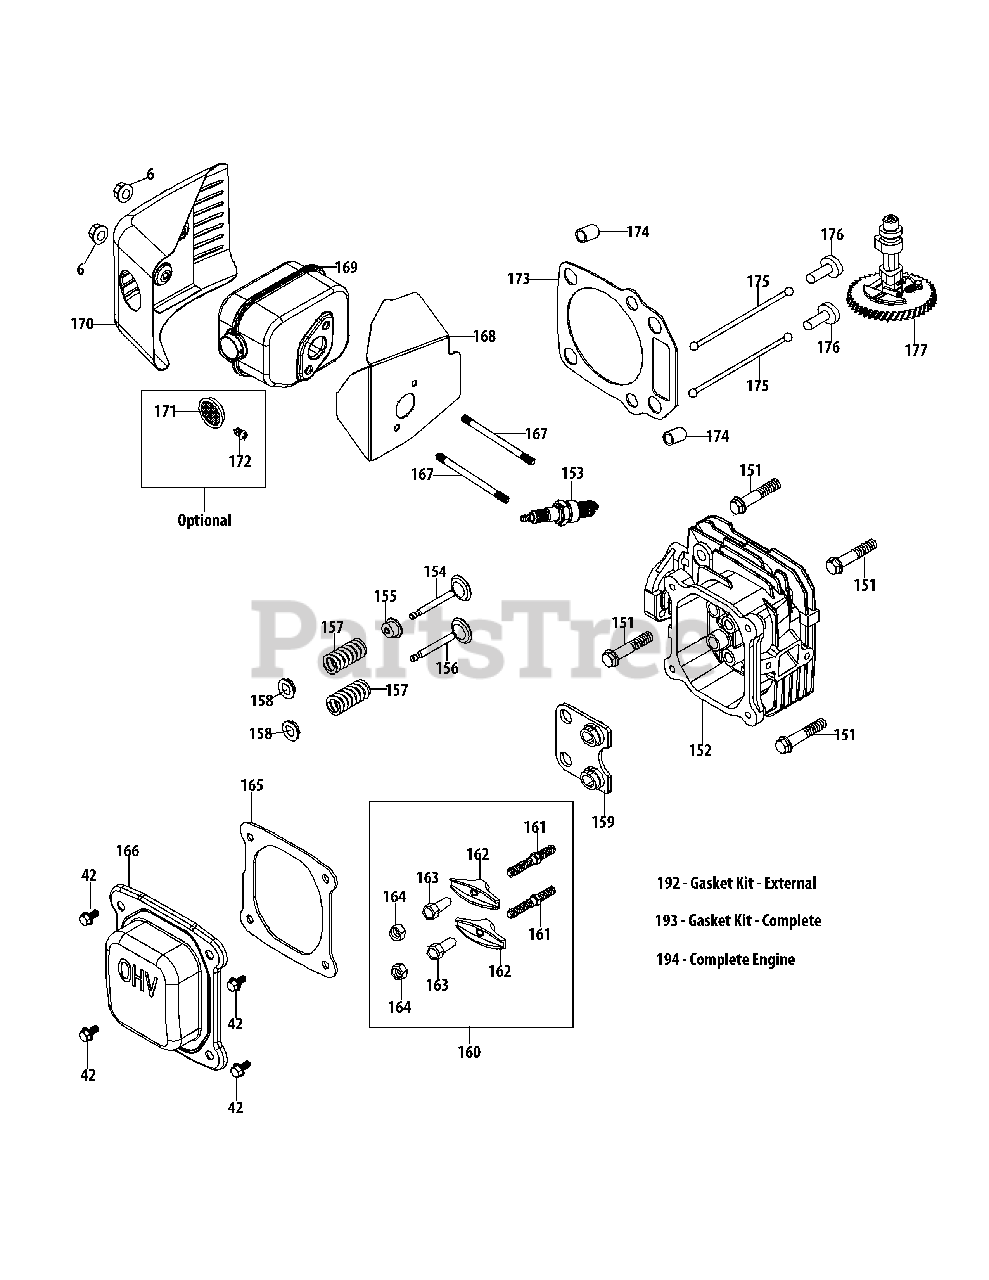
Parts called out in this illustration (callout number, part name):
6	Nut M6 X 10 Mm
42	Bolt M6X14
151	Bolt M8X54
152	Cylinder Head Svc Kit
152	Cylinder Head Assembly
153	Spark Plug/F6Rtc
154	Intake Valve
155	Intake Valve Seal
156	Exhaust Valve
157	Valve Spring
158	Valve Spring Retainer
159	Push Rod Guide
160	Rocker Arm Assembly
161	Rocker Arm Stud
162	Rocker Arm
163	Fulcrum Nut
165	Valve Cover Gasket
166	Valve Cover
167	Muffler Stud M6X95
167	Muffler Stud Assemlby
168	Muffler Gasket
169	Muffler Assembly
170	Muffler Shield
171	Spark Arrestor
172	Spark Arrestor Screw
173	Cylinder Head Gasket
174	Cylinder Head Dowel Pin 10×16
175	Push Rod Kit
177	Camshaft Assembly
192	Gasket Kit - External
193	Gasket Kit - Complete
194	Complete Engine
